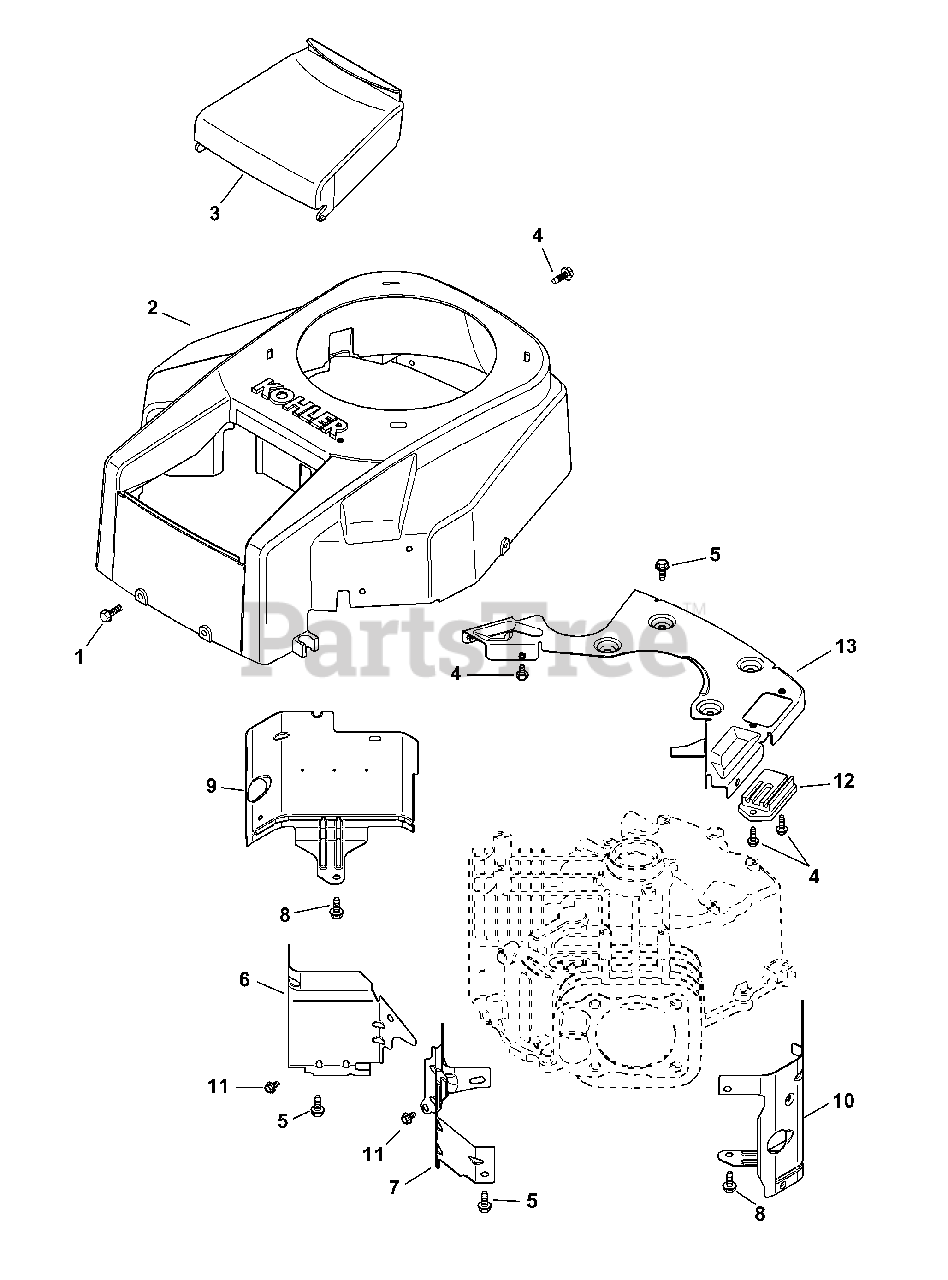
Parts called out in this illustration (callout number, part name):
1	Tap Screw, M6 x 1.7 x 18
2	Housing Blower Kit
3	Air Cleaner Cover
4	Flg. Thd. Frm. Screw, M5 x 0.8 x 16
5	Flg. Thd. Frm. Screw, M6 x 1.0 x 16
6	Valley Baffle - #1 Cylinder
7	Valley Baffle - #2 Cylinder
8	Flng. Thd. Frm. Screw, M6 x 1.0 x 10
9	Cyl Barrel Baffle - #1 Side
10	Cyl Barrel Baffle - #2 Side
11	Flg. Thd. Frm. Screw, M5 x .8 x 10
13	Backing Plate Kit
